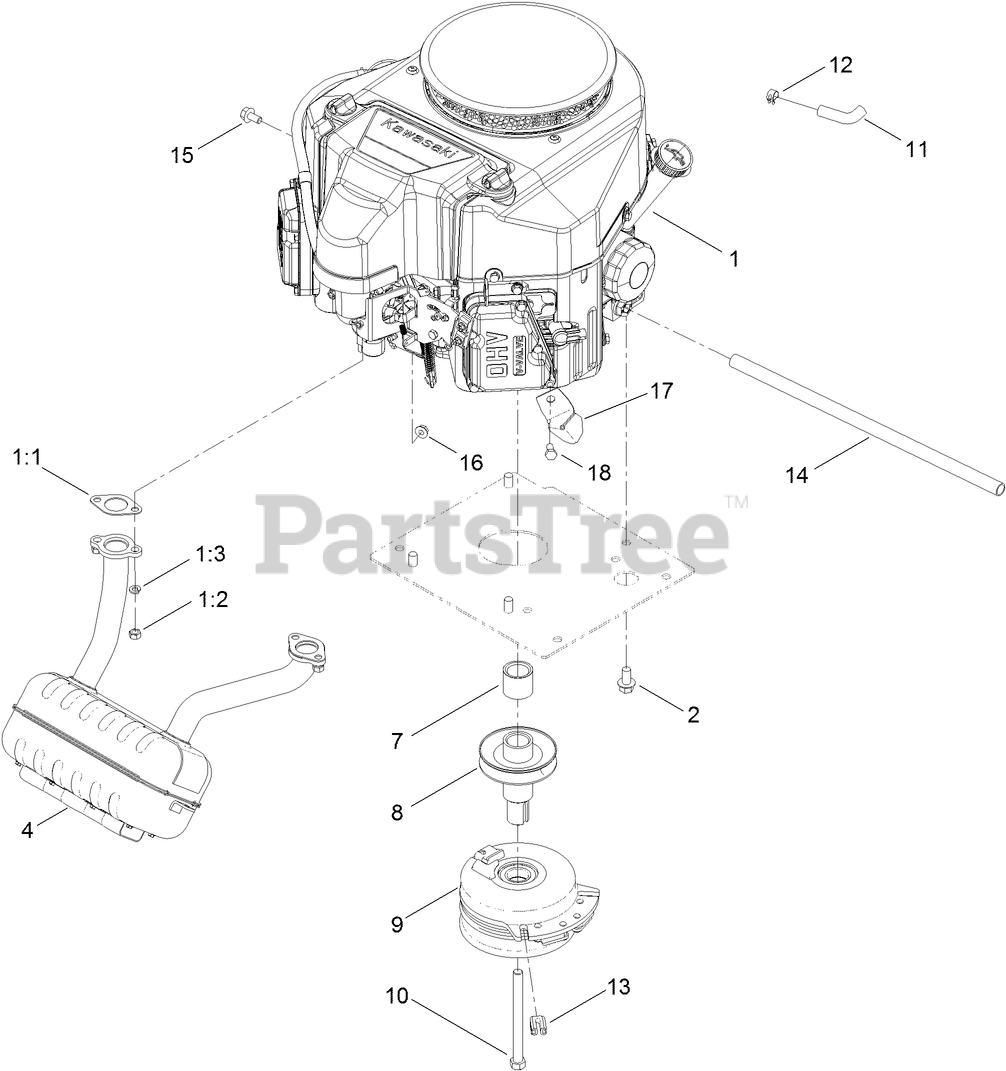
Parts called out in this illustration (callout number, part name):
1:1	GASKET-EXHAUST
1:3	WASHER-LOCK
2	SCREW-HHF
4	MUFFLER-TWIN, KAWASAKI
7	SPACER
8	PULLEY-ENGINE
9	CLUTCH-ELECTRIC
10	SCREW-HH
11	HOSE-FUEL
12	CLAMP-HOSE
13	ISOLATOR-CLUTCH
14	TUBE-DRAIN, OIL
15	SCREW-HHF
16	NUT-HF
17	SHIELD-SPARK
18	SCREW-HH
